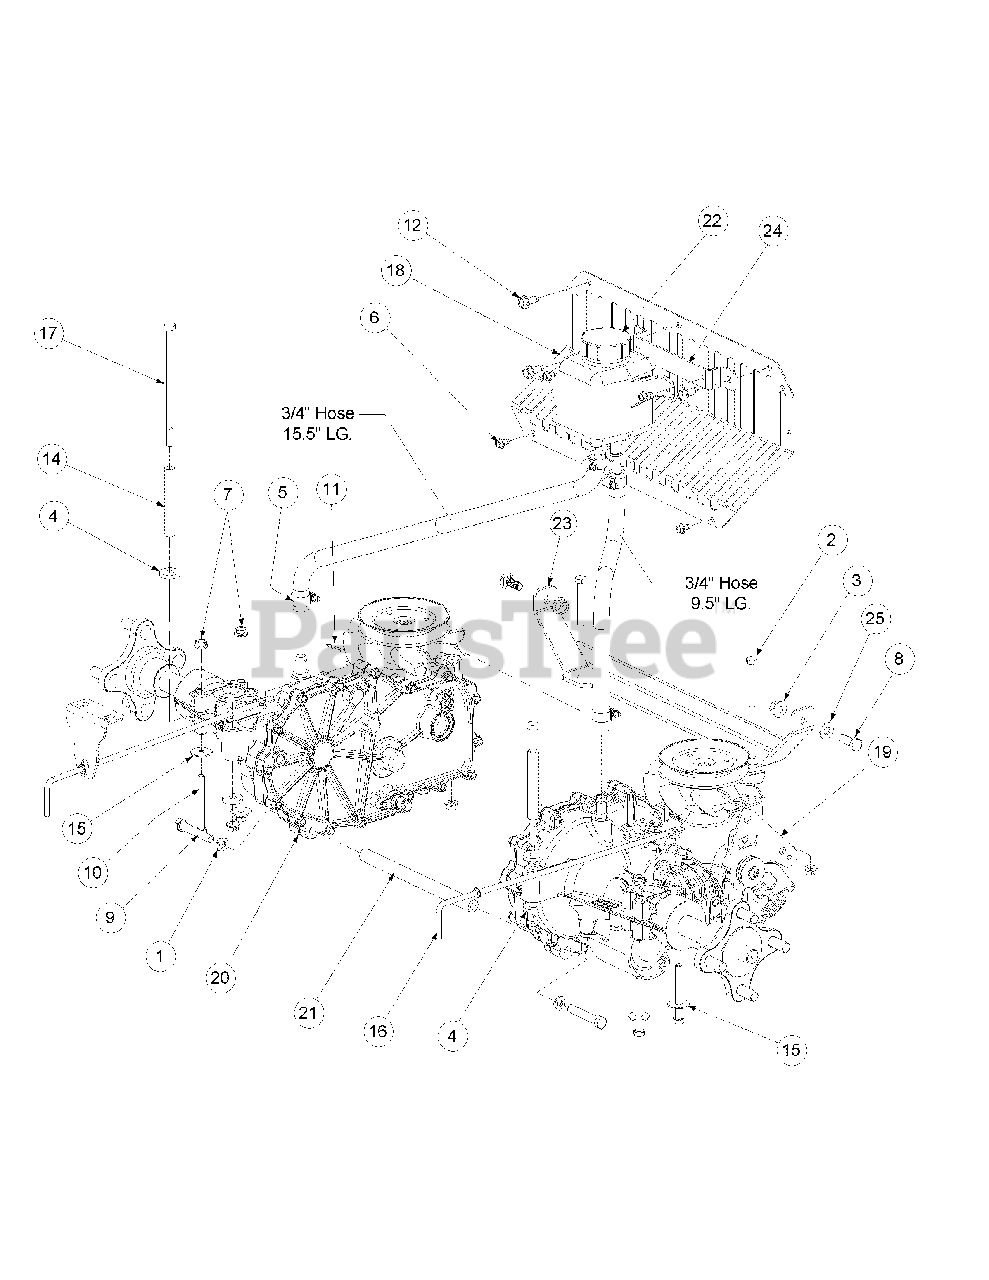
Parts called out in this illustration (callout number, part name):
1	Lock Washer, 3/8
2	Hex Cap Screw, 5/16-18 x 2.25
3	Flange Lock Hex Nut, 3/8-16
4	idler Washer
5	Hose Clamp
6	Screw, TT, 1/4-20 x .5, Hex Index Washer
7	Hex Flange Lock Nut, 5/16-18
8	Hex Cap Screw, 3/8-16 x 1.00
9	Hex Cap Screw, 3/8-16 x 2.25
10	Hex Cap Screw, 5/16-18 x 2.75
11	Cotter Pin, .072 x 1.12 Long
12	Self Tapping Screw 5/16-18 x .750
13	Fuel Hose, .50 ID x .75 OD
14	Spacer, .370 ID x .500 OD x 3.45
15	Washer, 5/16 x 1.06
17	Hex Cap Screw, 5/16-18 x 6.00
18	Pump Screen
19	Transmission Assembly, RH
20	Transmission Assembly, LH
21	Transmission Support Tube
22	Hydraulic Tank
23	Transmission Brace Weldment
24	Hydraulic Tank Bracket
25	Flat Washer, 3/8
